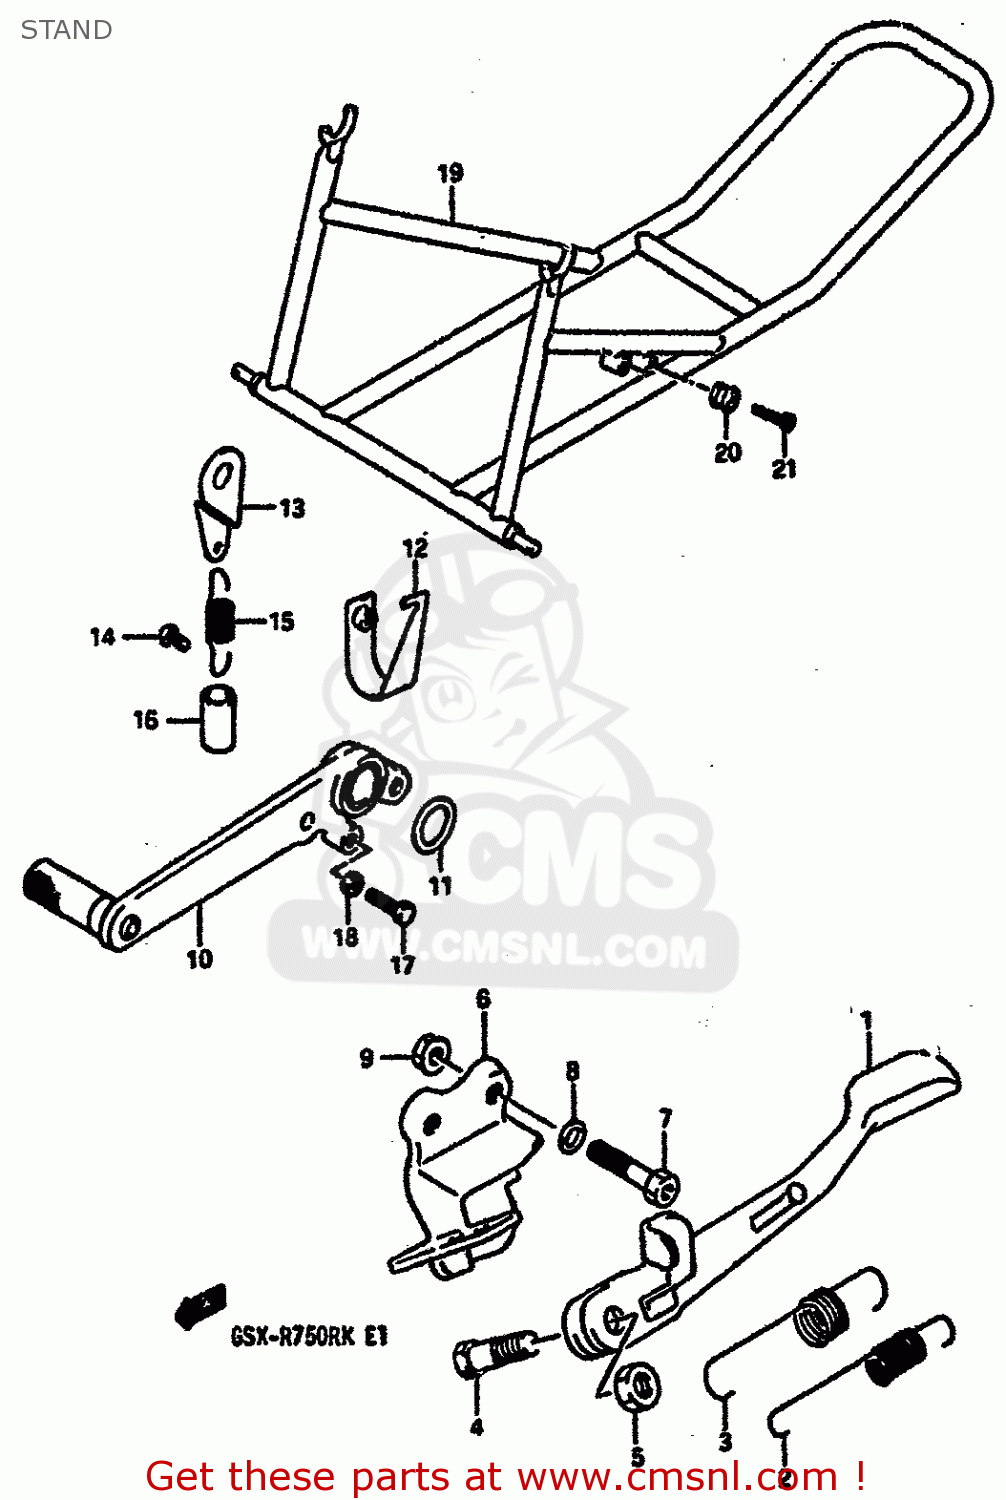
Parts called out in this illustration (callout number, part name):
1	STAND,PROP
2	SPRING
3	SPRING
4	BOLT(10X38)
5	NUT
6	BRACKET COMP,PROP STAND
7	BOLT, FRONT RH
8	WASHER
9	NUT
10	PEDAL,BRAKE
11	WASHER(18X24X1)
12	PLATE,BRAKE SPRING,FRONT
13	BRACKET,STOP SWITCH SPRING
14	SCREW(6X12)
15	SPRING
16	TUBE,BRAKE SPRING GUIDE
17	BOLT
18	NUT
19	STAND ASSEMBLY,REAR
20	HOLDER,STAND
21	BOLT, REAR (8X30)
